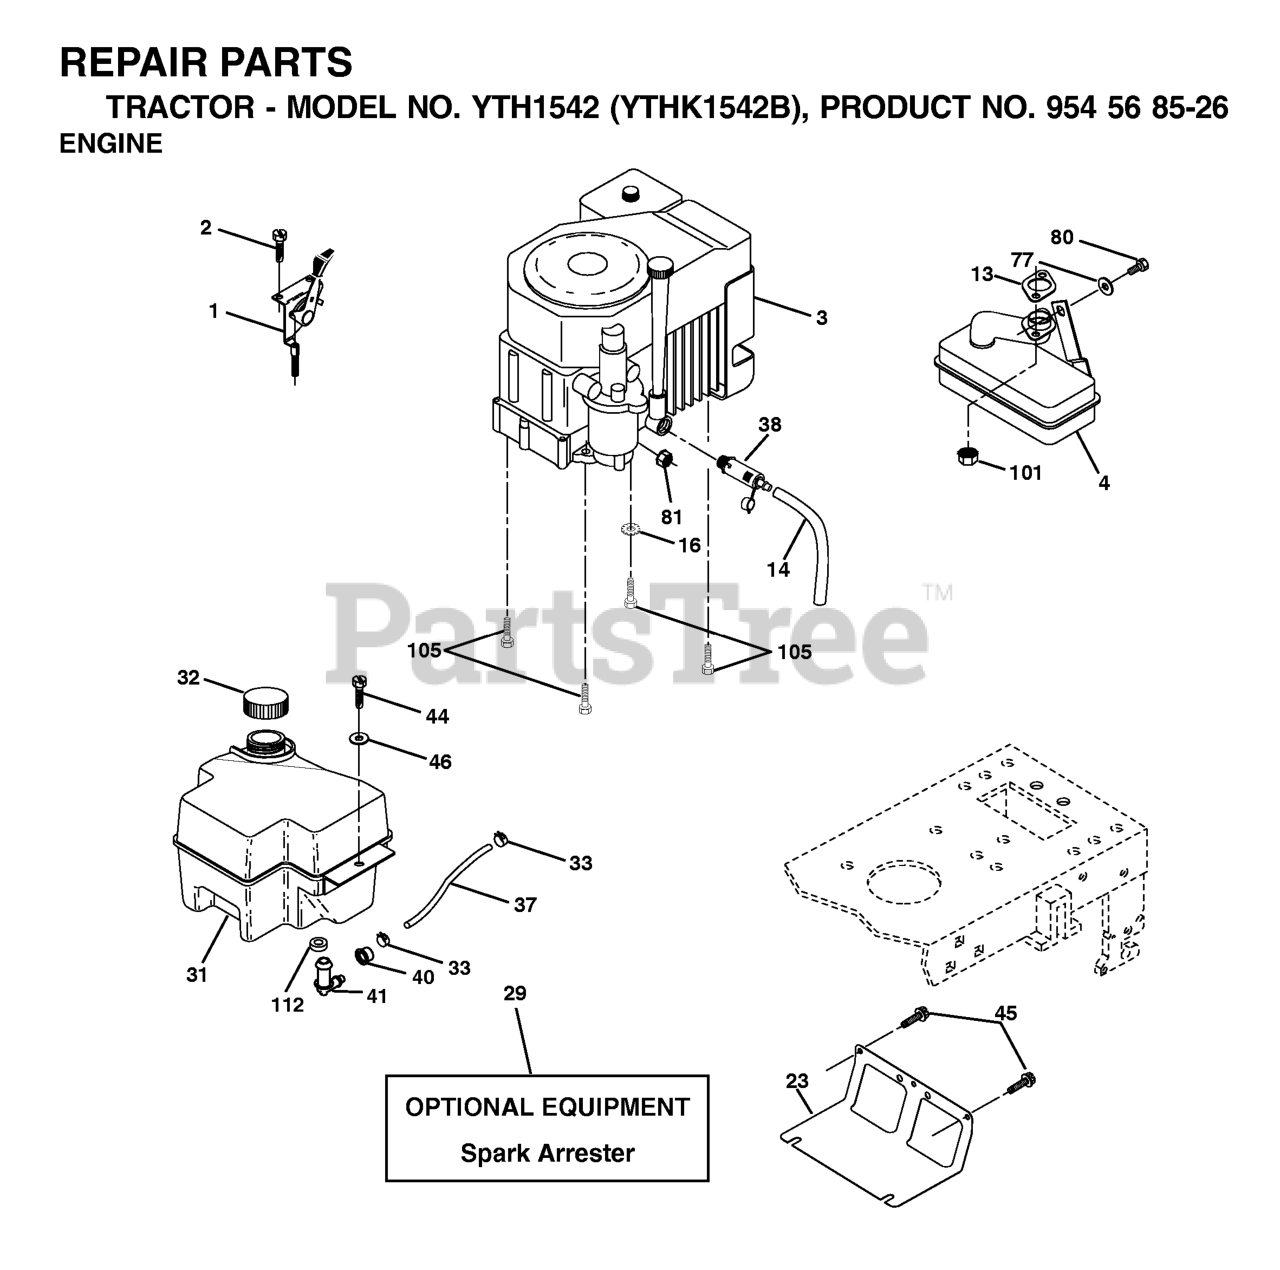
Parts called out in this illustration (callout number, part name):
1	CONTROL.THROTTLE.LT/YT
2	SCREW
4	MUFFLER.KOHL.CV.SINGLE.W/PORT
14	TUBE, DRAIN OIL ASM.
16	LOCKWASHER
23	SHIELD.BROWNING.DBR.GUARD
29	KIT.SPARK ARRESTOR 794945 B&S
31	GAS TANK 2GAL
32	FUEL CAP
33	HOSE CLAMP
37	LINE.FUEL.20
38	PLUG, OIL DRAIN EASY
40	BUSHING.SNAP.NYL.BLK.
41	STEM FUEL TANK
44	SCREW HEXWSHR 1/4-20X3/4
45	SCREW, 3/8-16X3/4
46	WASHER
62	WASHER.LOCK.HVY.HLCL.SPR.5/16
77	WASHER
80	Bolt, Hex Head, Fin. 5/16-18 x 1/2
81	NUT
101	FLANGE NUT
105	SCREW 3/8-16X1
112	BUSHING OUTLET T
